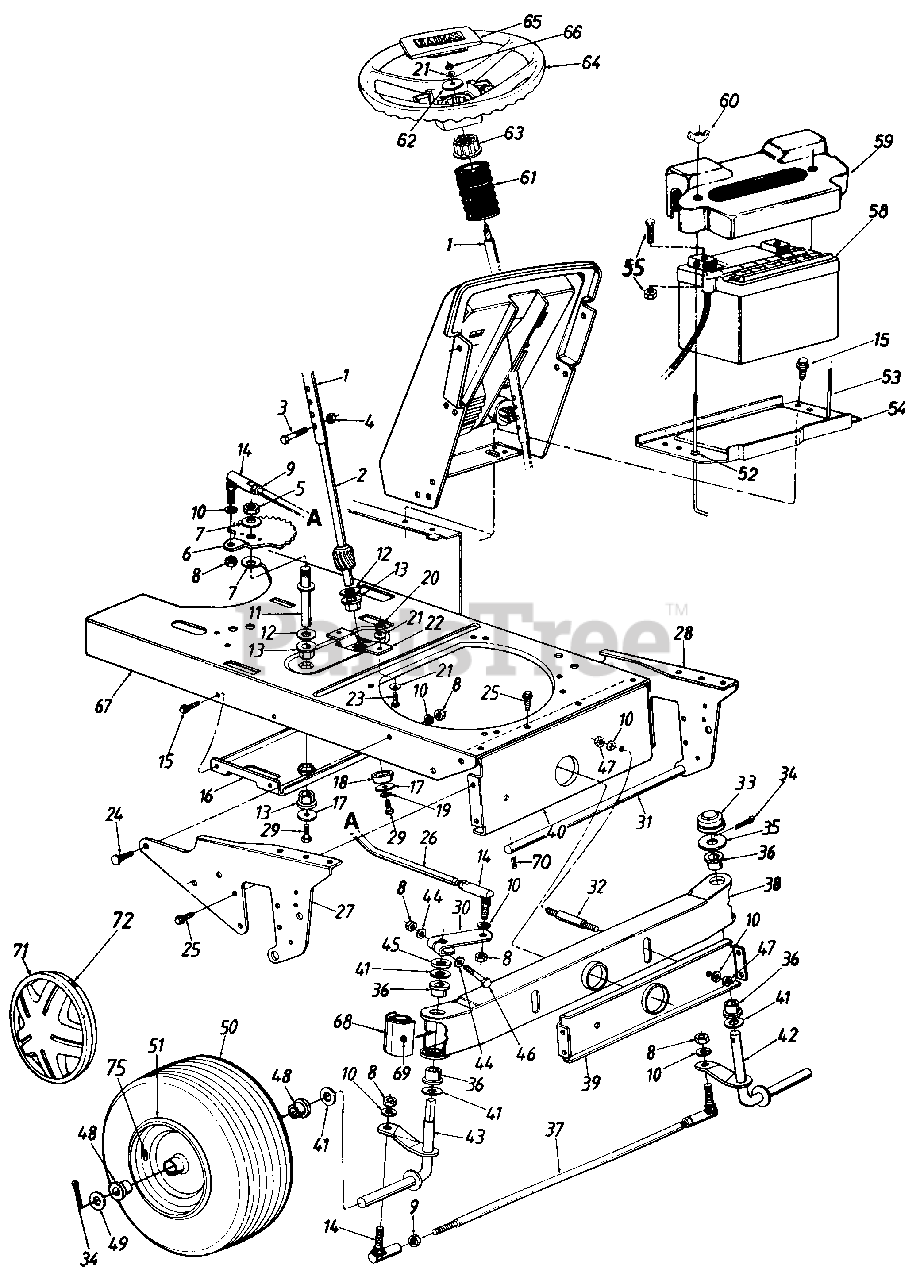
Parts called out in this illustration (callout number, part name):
1	Steering Column Ass'y.
2	Lower Steering Shaft
3	Hex Bolt 1/4-20 x 1.31" Lg.
4	Hex L-Nut 1/4-20 Thd.
5	Hex Nut 5/8-18 Thd.
6	Steering Gear Segment
7	Bell-Wash. 5/8" l.D. x 1.25" O.D.
8	Hex Nut 3/8-24 Thd.
9	Hex Jarn Nut 3/8-24 Thd.
10	L-Wash. 318" I.D.
11	Steering Gear Segment Shaft
12	Fl-Wash. .64" I.D. x 1.24' O.D.
13	Hex Flange Brg. .63" I.D.
14	Ball Joint Ass'y.
15	Hex Wash. Hd. TT-Tap Scr. 1/4-20 X .5" Lg.
16	Deck Idler Support Brkt.
17	Fl-Wash. .33" I.D. x 1.25" O.D.
18	Spacer .985" l.D. x 1.25" O.D.
19	L-Wash. 5/16" l.D.
20	Hex Nut 5/16-24 Thd.
21	Bell-Wash. .345" l.D. x .88" O.D.
24	Ribbed Neck Bolt 3/8-24 x .8" Lg.
25	Hex Wash. TT-Tap Scr. 5/16-18 x .62" Lg.
26	Steering Drag Link
27	Pivot Bar Side Plate-R.H.
28	Pivot Bar Side Plate-L.H.
29	Hex Bolt 5/16-18 x .62" Lg.
30	Steering Arm
31	Deck Connecting Rod
32	Pivot Bar Shld. Bolt 3/8-16 x 5/8" Lg.
33	Cap
34	Cotter Pin 5/32" Dia.
36	Flange Brg. 757" l.D.
37	Tie Rod 20.25" Lg.
38	Pivot Bar Assy.
41	Fl-Wash. 76" l.D. x 1.49" O.D.
42	Front Axle Ass'y.-L.H.
43	Front Axle Ass'y.-R.H.
44	Bowed Washer
45	Spacer .755" I.D. x 1.25" O.D.
46	Hex Bolt 3/8-24 x 2.25" Lg.
47	Hex Nut 3/8-16 Thd.
48	Bronze Flange Brg.
49	Fl-Wash. .71" l.D. x 1.5" O.D.
50	Wheel Ass'y. Comp.
51	Rim Only
52	Push Nut
53	Battery Hold Down Rod
54	Battery Plate
55	Comes w/Battery
58	Battery (275 Cold Crank Amps)
59	Battery Cover
60	Wing Nut Plastic 1/4-20 Thd.
61	Steering Bellow
62	Flat Washer
63	Steering Wheel Adapter
64	Steering Wheel
65	Steering Wheel Cap
66	Hex L-Nut 5/16-24 Thd.
67	Lower Frame
68	Pivot Bar End Cap
69	Grease Fitting
70	Internal Cotter Pin
71	Hub Cap
72	Spring Clip
75	Air Valve
